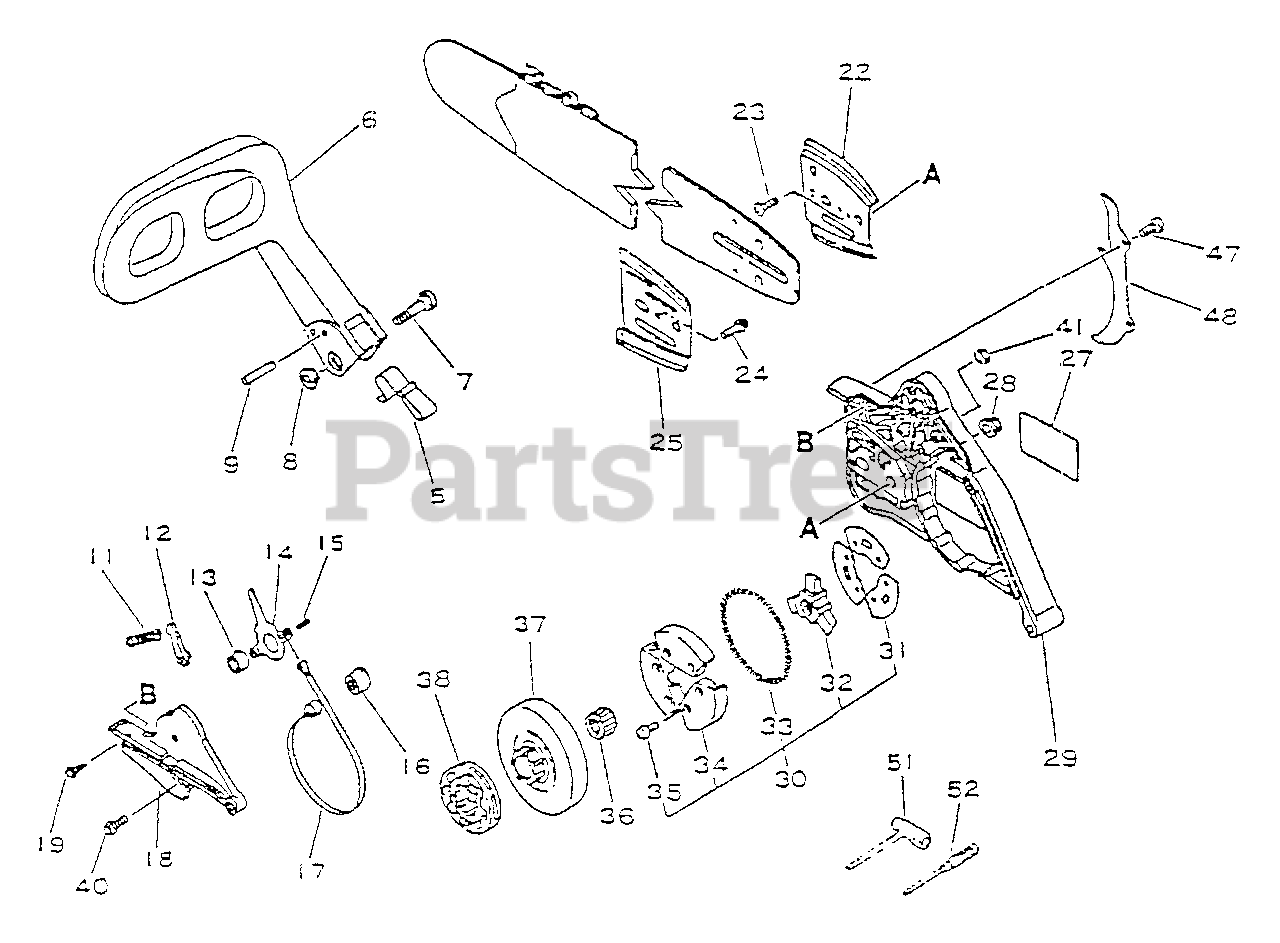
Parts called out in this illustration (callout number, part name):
5	SPRING, RETURN
6	LEVER, BRAKE
7	MOUNTING KIT
9	PIN - 3.5X26
11	SPRING, BRAKE
12	STOPPER, BRAKE
13	SPACER - 8
14	LEVER, BRAKE
15	PIN - SPRING -- 4X8
16	ADJUSTER, BRAKE BAND
17	BAND, BRAKE
18	COVER, BRAKE
19	SCREW - 4X12
22	PLATE, GUIDE - OUTER
23	SCREW - 3X6
24	SCREW - 4X8
25	PLATE, GUIDE - INNER
27	LABEL - ECHO
28	NUT - FLANGE
29	GUARD, SPROCKET
30	CLUTCH ASSY
31	PLATE, CLUTCH
32	HUB, CLUTCH
33	SPRING, CLUTCH
34	CLUTCH SHOE SET
35	SCREW - 4X6
36	BEARING, NEEDLE
37	DRUM, CLUTCH
38	SPROCKET, RIM
40	SCREW - 3X18
48	SPIKE KIT
51	T-WRENCH - 13X19mm
52	SCREWDRIVER
